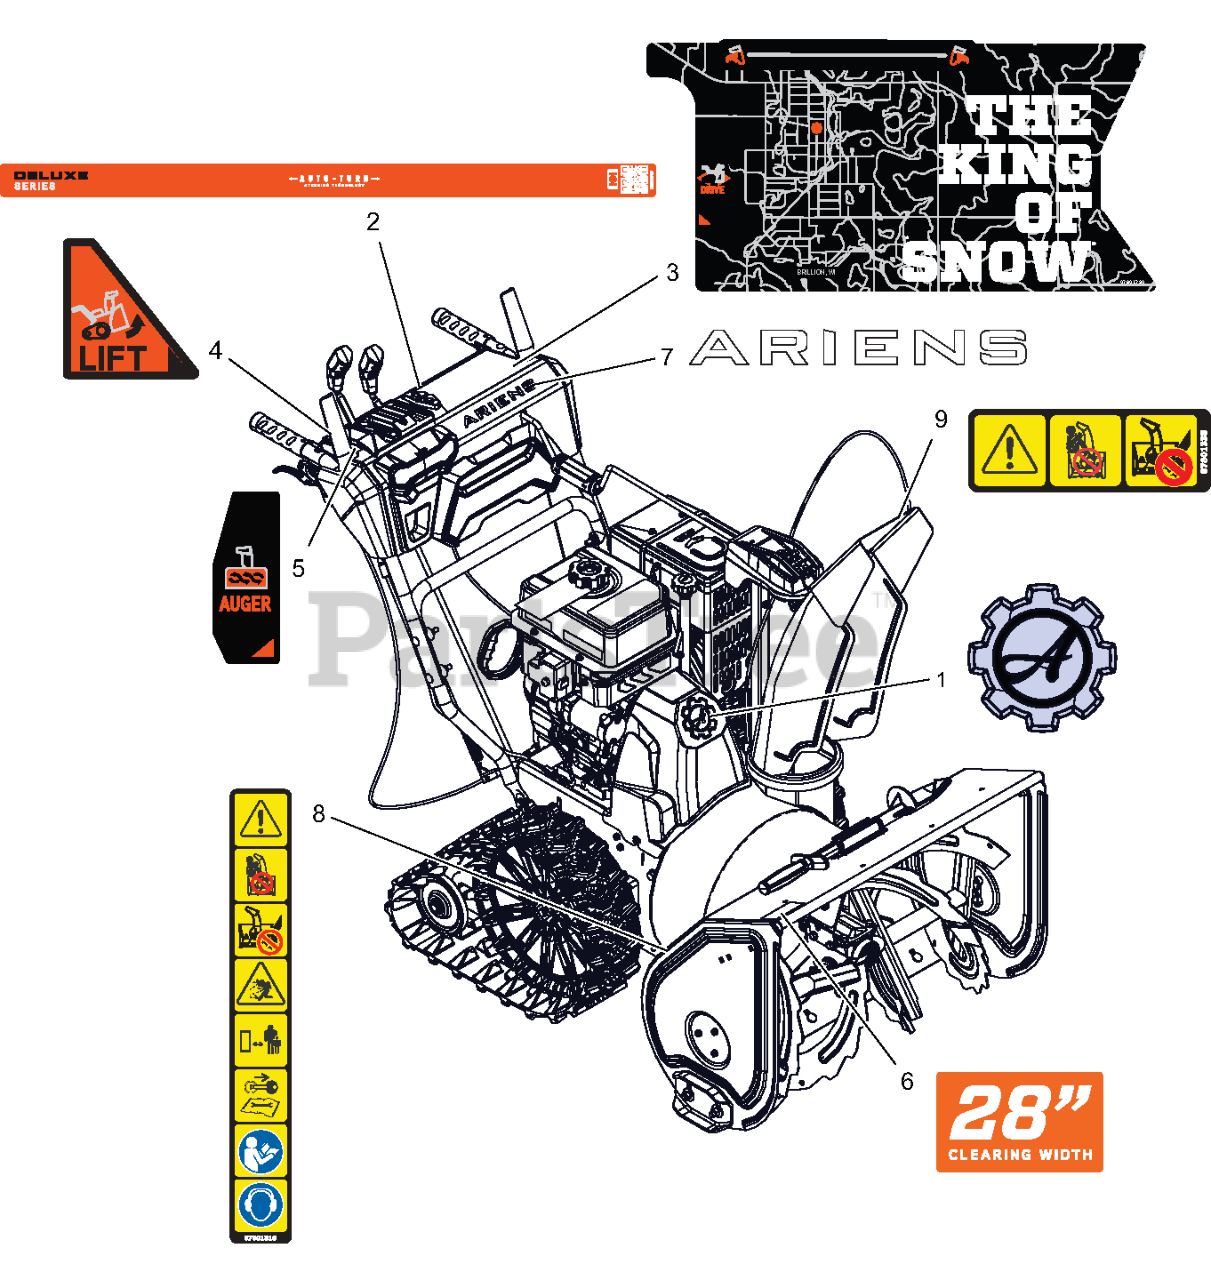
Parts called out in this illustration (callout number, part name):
1	DECAL- ARIENS GEAR BADGE
2	DECAL- DASH DLX RT
3	DECAL- CONTROL - LG RT ICEDRIL
4	DECAL- CONTROL - TRACK LIFT
5	DECAL- CONTROL - AUGER
6	DECAL- CLEARING - 28
7	DECAL- ARIENS - 7.46"
8	DECAL- SAFETY - DANGER
9	DECAL- DANGER
